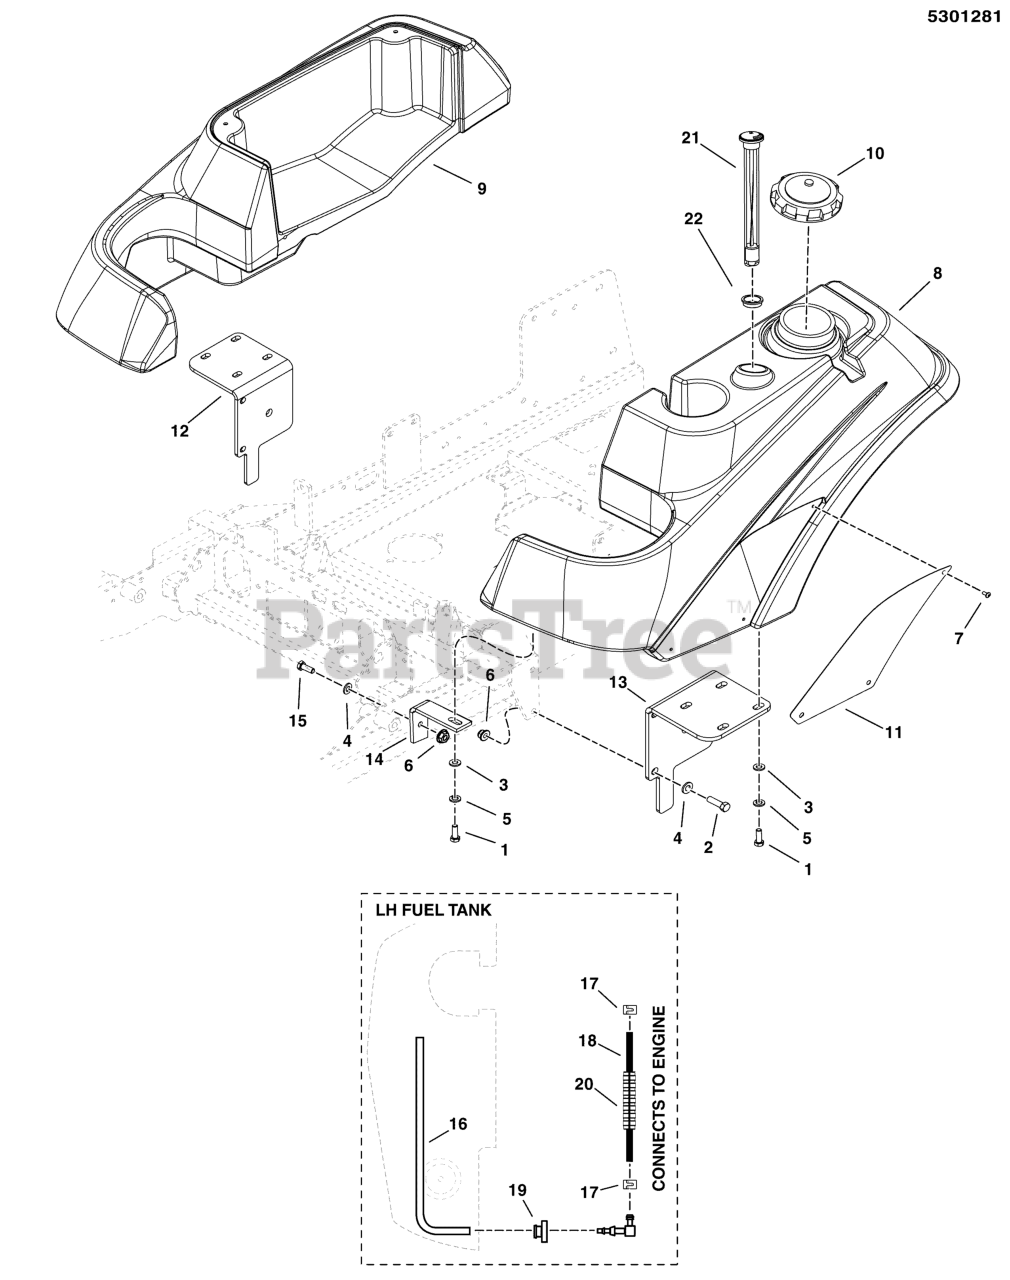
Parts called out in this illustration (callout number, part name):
1	BOLT, 5/16-18 X 1 GD5 YZ
2	BOLT, 3/8-16 X 1" GD5 CZ
3	WASHER, 5/16" SAE
4	WASHER, 3/8 SAE
5	WASHER, 5/16 LOCK CZ
6	NUT, 3/8-16 HEX NYLOCK FLANGE
7	SCREW, #10-24 X 3/8 ALLEN BHBZ
9	TANK, FENDER, 1500Z - RH
11	BADGE, IS1500Z, RED
14	MOUNT, TANK, FRONT - BLK
15	BOLT, 3/8-16 X 1-1/4" GD5 CZ
16	PICKUP TUBE ASM, FUEL TANK, 22"
17	CLAMP, HOSE, EXTERNAL, 1/2
18	HOSE, 1/4" FUEL, 8.00"
19	BUSHING-FUEL TANK RED RUBBER
20	WIRE LOOM, 1/2 ID X 5 IN
21	GAUGE, FUEL, 12
22	GROMMET, FUEL GAUGE
